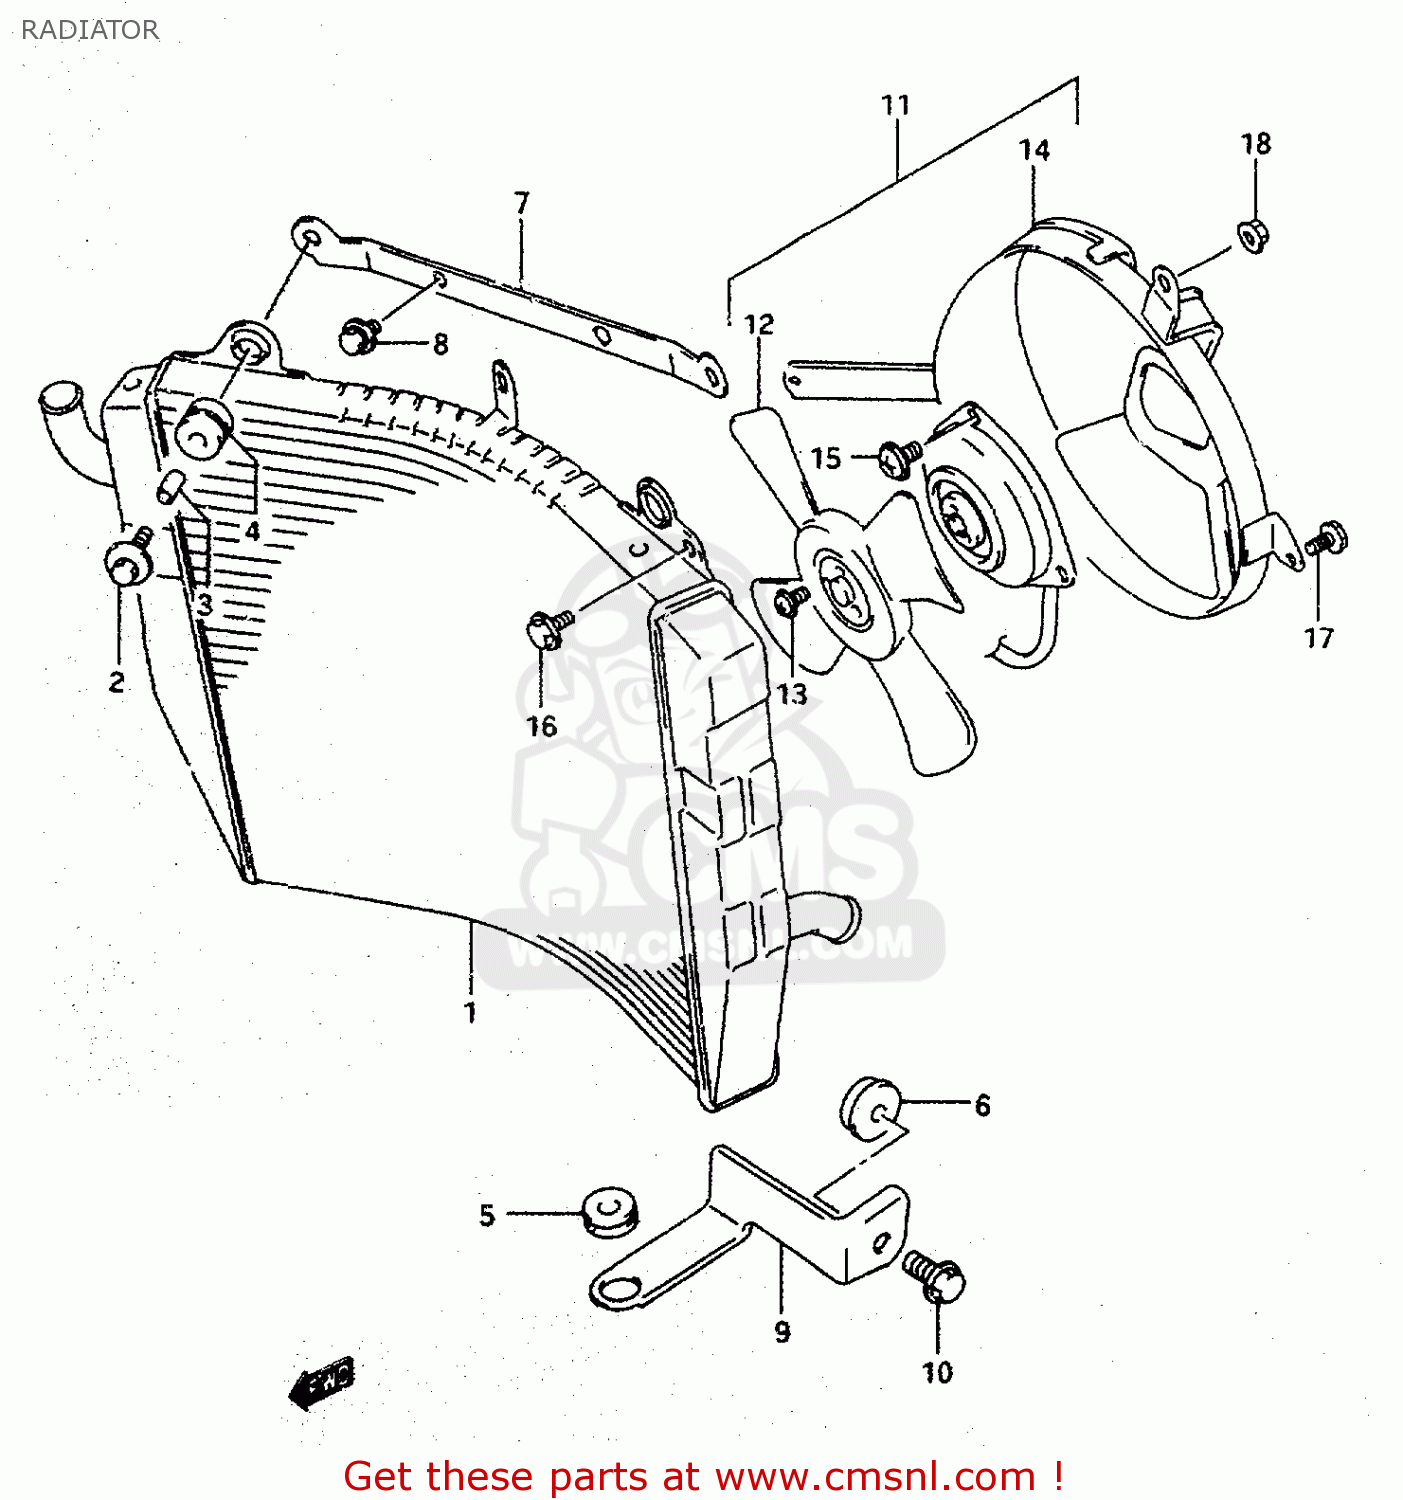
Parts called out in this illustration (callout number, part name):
1	RADIATOR ASSY,WATER
2	BOLT(6X25)
3	SPACER(6.5X10.5X12)
4	CUSHION,RADIATOR LWR
5	CUSHION
6	SPACER,RADIATOR BRACKET LWR
7	BRACKET COMP,RADIATOR
8	BOLT
9	BRACKET COMP,RADIATOR
10	BOLT
11	FAN ASSY,RADIATOR
12	FAN
13	BOLT
14	SHROUD ASSY,FAN
15	BOLT
16	BOLT
17	BOLT
18	NUT
